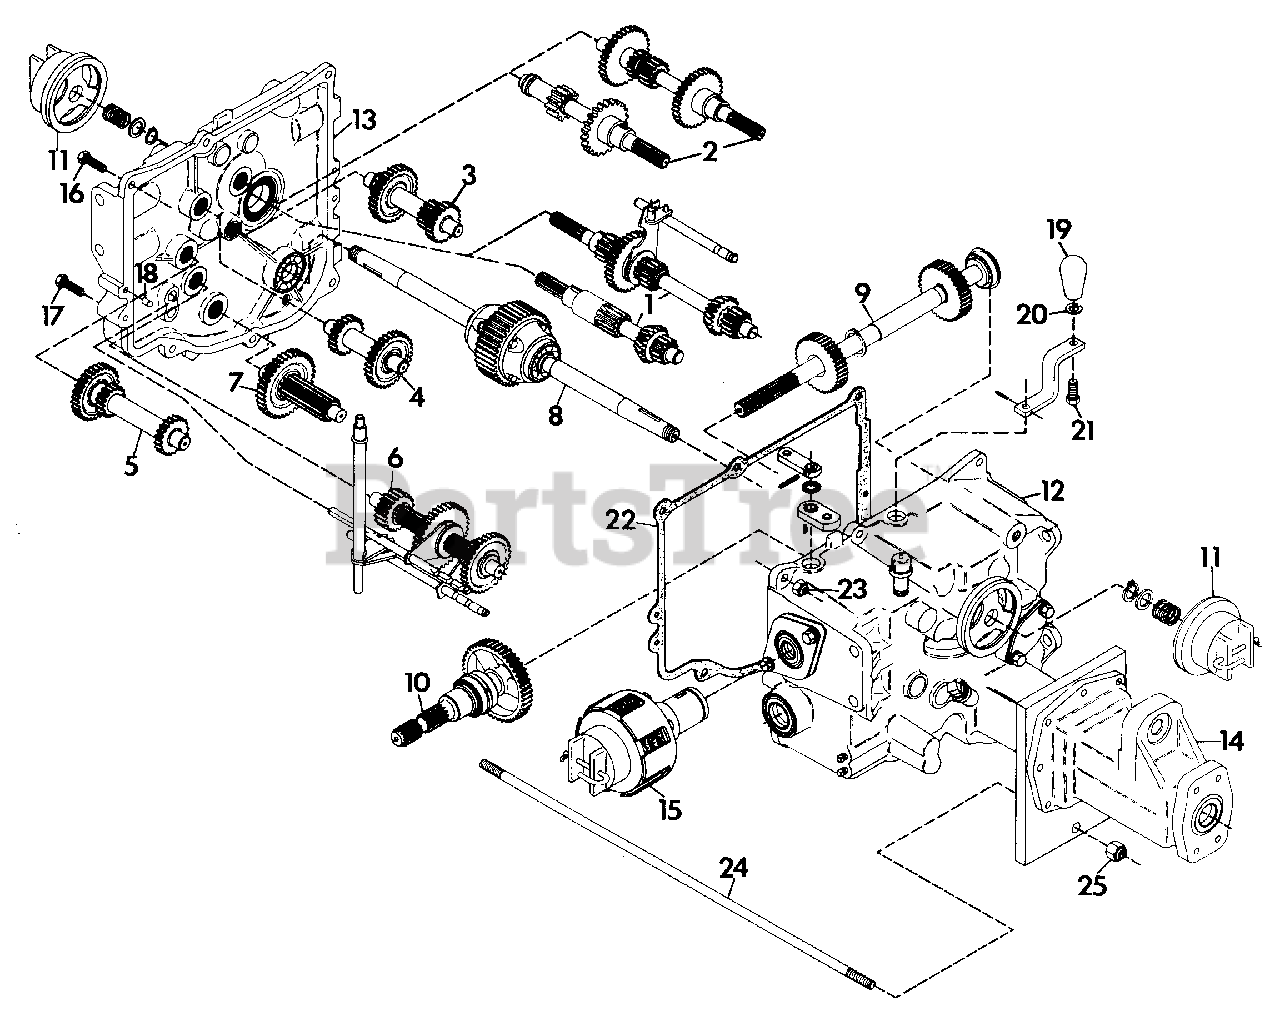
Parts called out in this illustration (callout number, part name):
1	NUMBER 1 SHAFT - FORWARD CLUTCH
2	NUMBER 2 SHAFT - REVERSE CLUTCH
3	NUMBER 3 SHAFT - 3RD AND 4TH GEAR
4	NUMBER 4 SHAFT - IDLER
5	NUMBER 5 SHAFT - 1ST AND 2ND GEAR
6	NUMBER 6 SHAFT - BRAKE/SLIDING GEAR
7	NUMBER 7 SHAFT - PINION/FINAL DRIVE
8	NUMBER 8 SHAFT - DIFFERENTIAL ASM.
9	NUMBER 9 SHAFT - PTO CLUTCH SHAFT
10	NUMBER 10 SHAFT - PTO DRIVE ASSEMBLY
11	NUMBER 11 - FWD-REV CLUTCH ASSEMBLY
12	NUMBER 12 - TRANSMISSION CASE ASM.
13	NUMBER 13 - TRANSMISSION COVER ASM.
14	NUMBER 14 - AXLE HOUSING
15	NUMBER 15 - PTO CLUTCH ASSEMBLY
16	BOLT, HEX 3/8-16X1.50
17	BOLT, HEX 3/8-16X2.25
18	PIN, DOWEL .375X.625
19	KNOB, PTO
20	WASHER, LOCK 1/2 REG.
21	BOLT, HEX 1/2-13X.875
22	GASKET, TRANSMISSION COVER
23	NUT, LOCK 3/8-16
24	ROD, STRUT
25	NUT, LOCK 1/2-13
